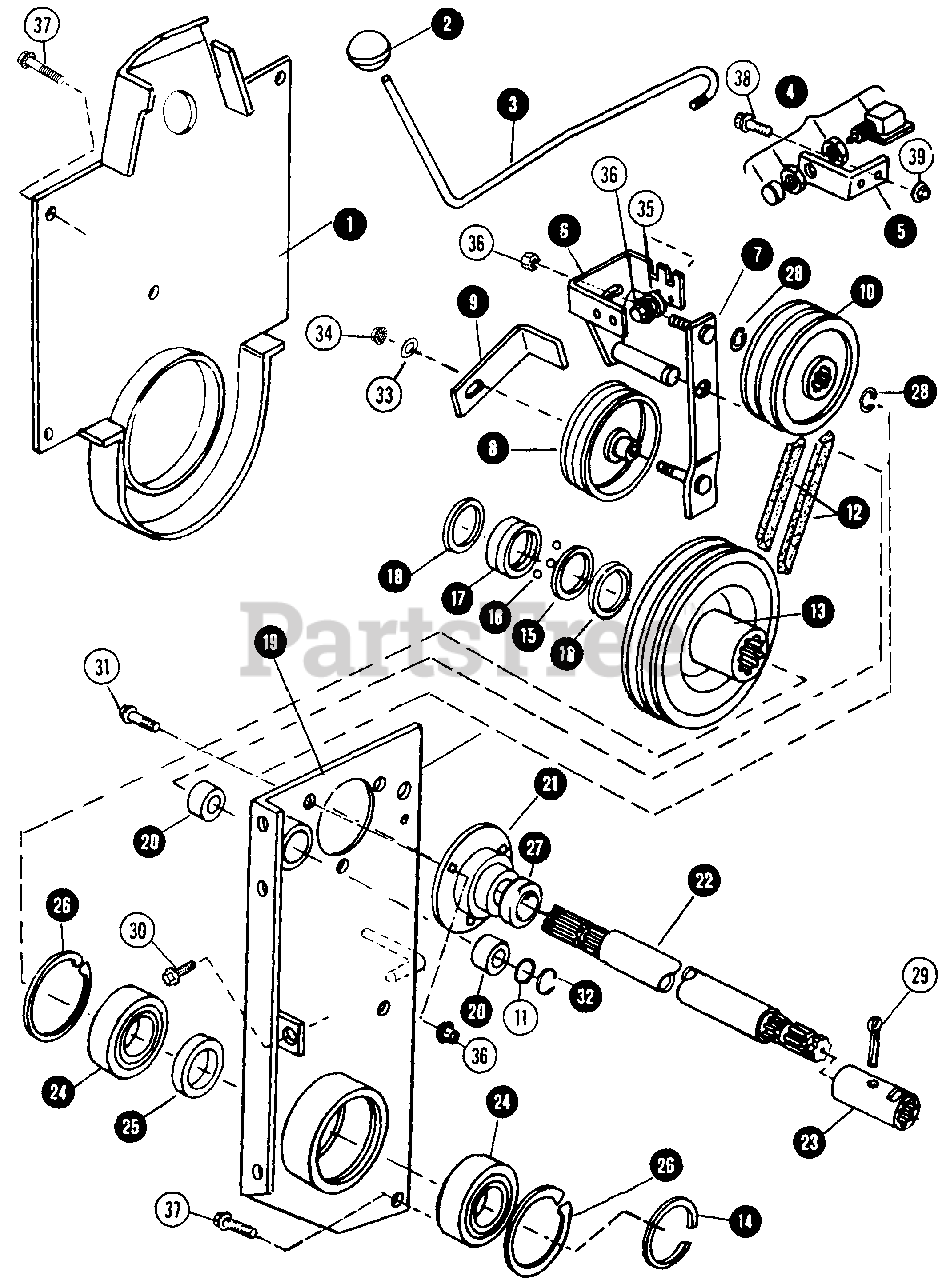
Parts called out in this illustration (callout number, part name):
1	COVER, REAR P.T.O.
2	KNOB, REAR P.T.O. LEVER
3	LEVER, P.T.O. CONTROL
4	INTERLOCK, REAR P.T.O. - ASSEMBLY
5	BRACKET, INTERLOCK MOUNTING
6	BRACKET, CONTROL LEVER
7	ARM, IDLER
8	PULLEY P.T.O. IDLER, 3/8" ID, 4.0" OD, 1.25" Wide
9	GUIDE, V-BELT
10	PULLEY, P.T.O. DRIVE
11	SHIM, .632 I.D. x .020"
12	V-BELTS (MATCHED SET)
13	PULLEY, REAR P.T.O.
14	RING, PULLEY RETAINING
15	SPRING SLIDING RETAINING
16	SALL, LOCK COLLAR BEARINGS (3/8 DIA.)
17	COLLAR, P.T.O. SHAFT LOCK
18	RING, LOCK COLLAR RETAINING
19	PLATE, P.T.O. MOUNTING ASSEMBLY
20	BUSHING MOUNTING PLATE
21	BEARING, 3 Hole Flanged Lock Collar Assy., 3/4" ID
22	SHAFT, REAR P.T.O. DRIVE
23	COUPLING, P.T.O. DRIVE SHAFT
24	BEARING, P.T.O. PULLEY, 1.37" ID, 2.83" OD, .66" Wide
25	SPACER, BEARING
26	RING, BEARING RETAINING
27	SPACER, P.T.O. SHAFT
28	RING, SHAFT RETAINING
29	COTTER-PIN, 1/4 x 1-1/2"
30	BOLT, 1/2C x 3/4 HEX FLANGE
31	BOLT, 5/16C x 1/8 HEX FLANGE
32	RING, RETAINING
33	WASHER, 3/8" Flat
34	NUT, 3/8C HEX FLANGE
35	SPACER, CONTROL LEVER BRACKET
36	NUT, 5/16C HEX FLANGE LOCK
37	BOLT, 3/8C x 3/4 HEX FLANGE
38	BOLT, 1/4C x 1/2 HEX FLANGE LOCK
39	NUT, 1/4C HEX FLANGE LOCK
